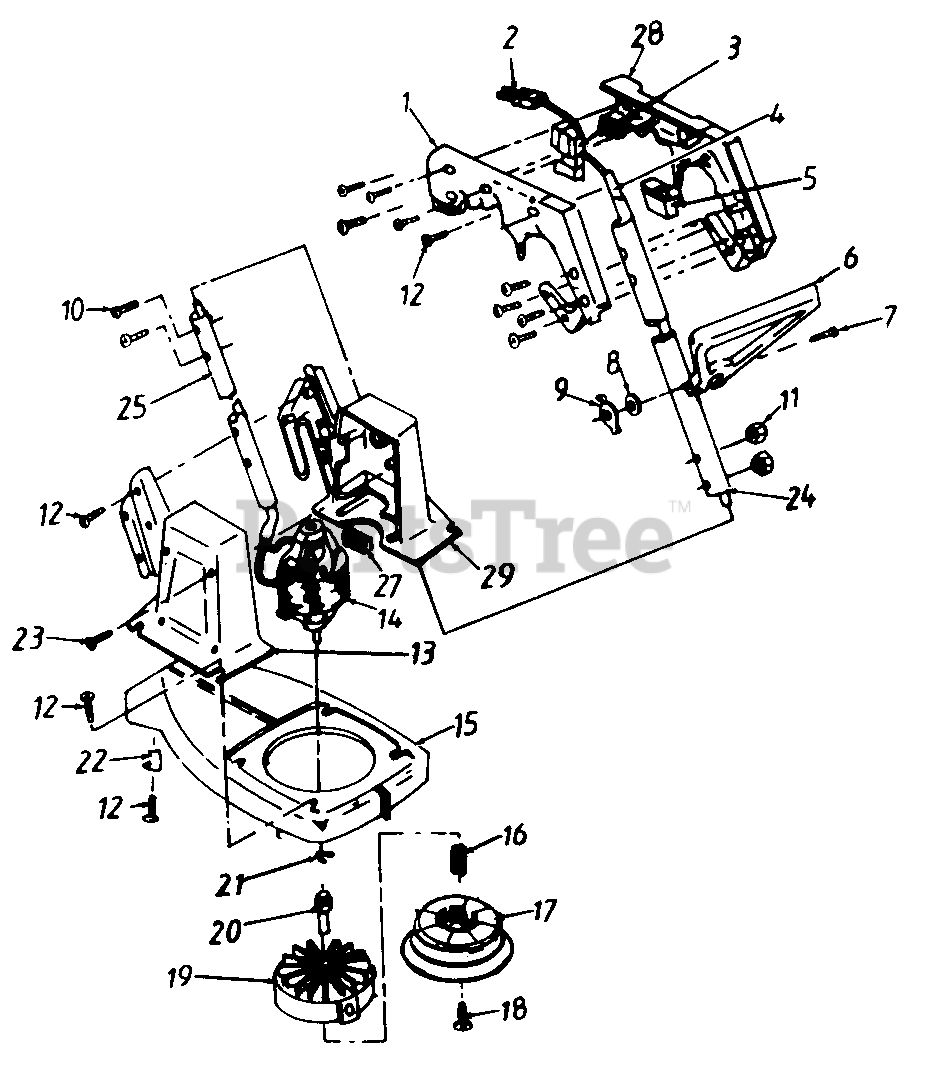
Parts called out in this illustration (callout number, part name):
1	Handle-Trigger R.H.
2	Cord Set (2 Prong)
3	Switch-Trigger
4	Wiring Harness
5	Switch-2 Speed
6	Balance Handle
7	Hex Bolt 1/4-20 x 2.25" Lg.
8	Fl-Wash. 1/4" I.D.
9	Wing Nut 1/4-20 Thd.
10	Scr. #10-24 x 1.25"
11	L-Nut #10-24 Thd.
12	Scr. #8 x 5/8" Lg.
13	Housing Motor R.H.
14	Motor
15	Guard
16	Spring
17	Cartridge
18	Nylon Scr. 1/4-20 x 5/8" Lg.
19	Spool Hsg. Ass'y.
20	Spool Shaft
21	Retaining Ring
22	Blade (2 Blades w/Screw)
23	Scr. #8 x 1.75" Lg.
24	Upper Handle Tube
25	Lower Handle Tube
27	Insulator
28	Handle-Trigger
29	Housing Motor
